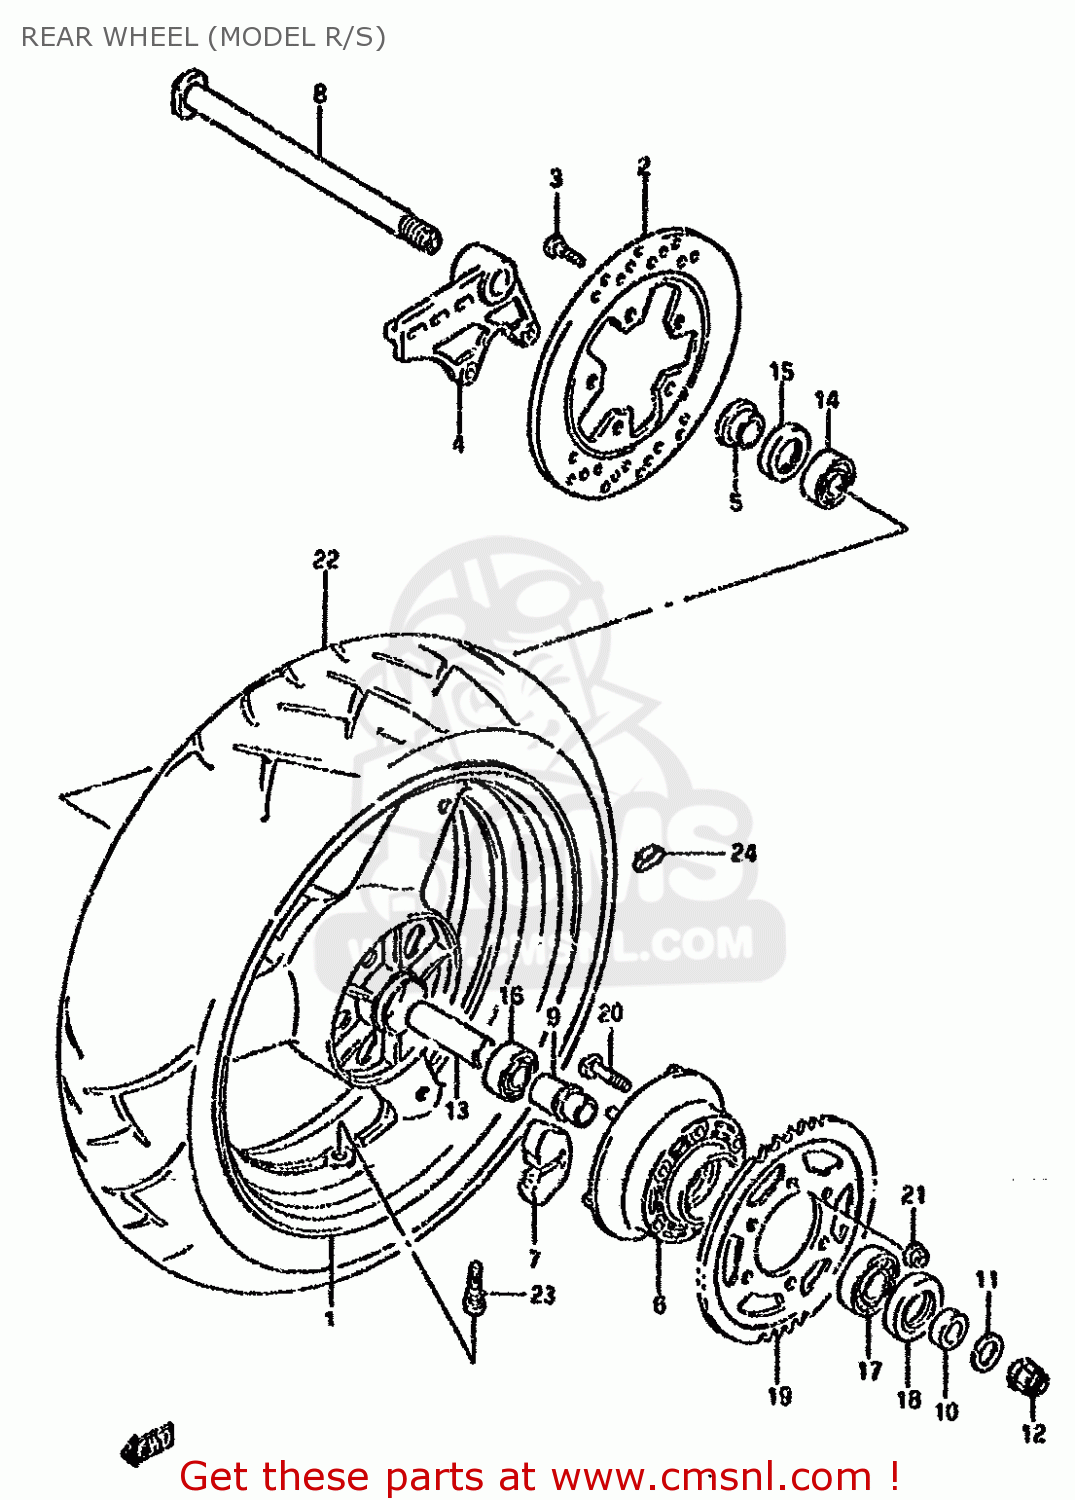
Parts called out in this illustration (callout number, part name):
1	WHEEL,REAR
2	DISC,RR BRAKE
3	BOLT 8X33
4	BRACKET,RR CALIPER
5	SPACER,RR AXLE,R
6	DRUM,RR SPROCKET
7	ABSORBER,RR HUB SHOCK
8	AXLE,RR
9	RETAINER,RR HUB BEARING
10	SPACER,RR AXLE,L
11	WASHER (18.2X28X2.6)
12	NUT
13	SPACER,RR WHEEL HUB BEARING
14	BEARING(20X47X14)
15	SEAL,OIL(28X47X7)
16	BEARING(20X47X14)
17	BEARING(25X62X17)
18	SEAL,OIL(35X62X8)
19	SPROCKET,RR(NT:42)
20	BOLT
21	NUT
22	TIRE,REAR (180/55 ZR17 D204) (DUNLOP)
23	VALVE ASSEMBLY,WHEEL,TR412
24	BALANCER,WHEEL
27	BALANCER,WHEEL
